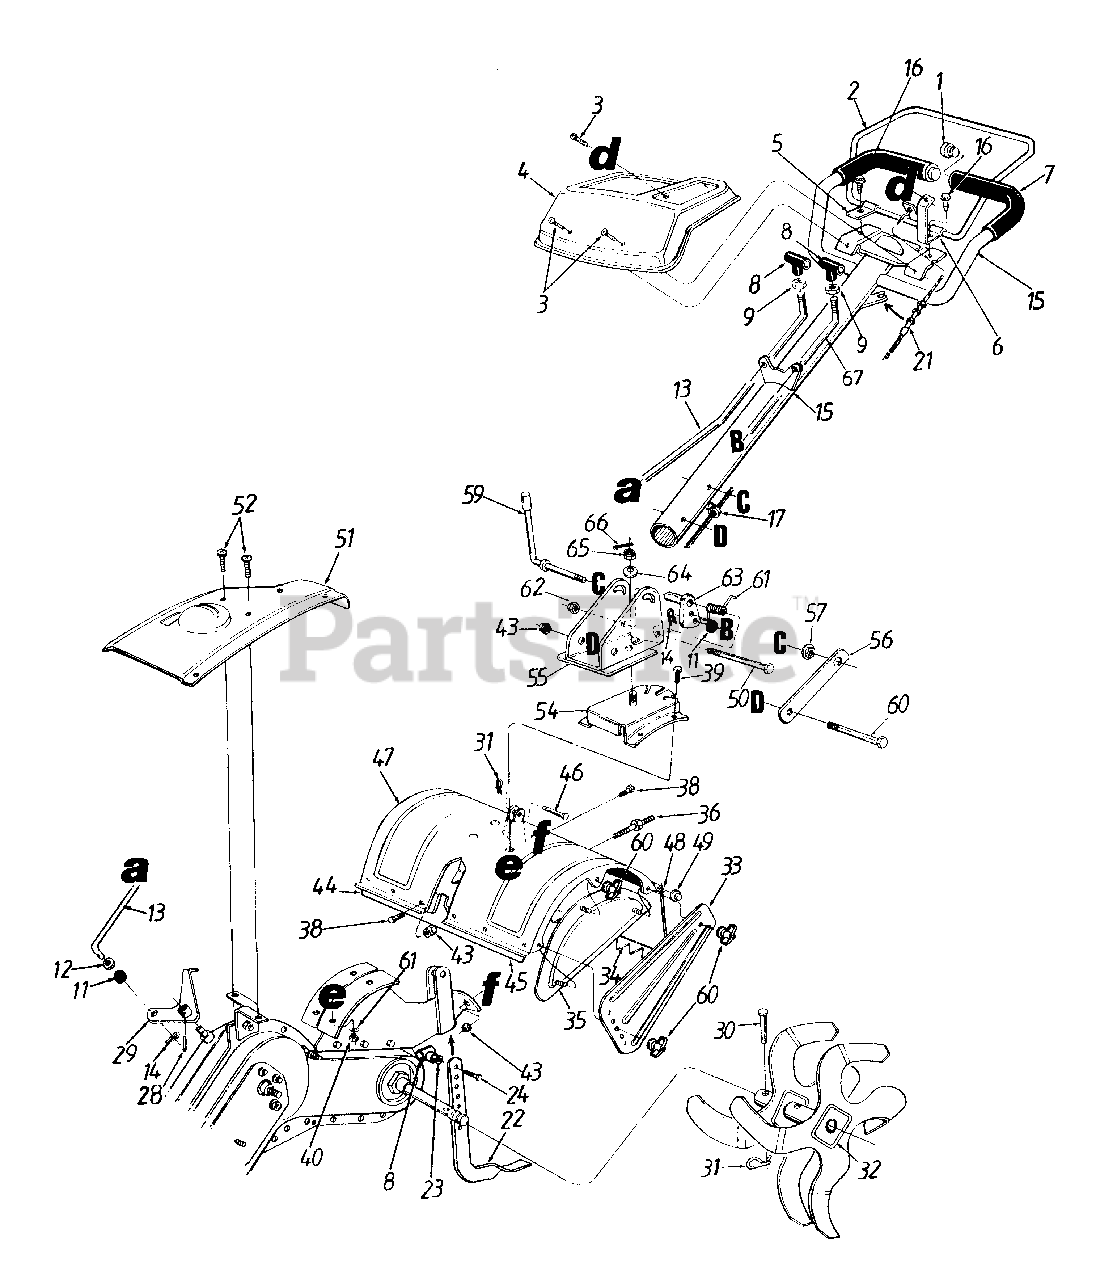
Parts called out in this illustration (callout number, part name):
1	Vinyl End Plug
3	Torx Mach. AB-Tap Scr. 1/4 x .62" Lg.
7	Grip
9	Hex Jam Nut 3/8-16 Thd.
11	Rubber Washer
12	Fl-Wash. .344" I.D. x .6" O.D.
13	Gear Shift Rod
14	Hairpin Clip
17	Cable Clip
21	Clutch Cable
23	Fl-Wash. 3/8" I.D. x 5/8" O.D.
24	Hex Bolt 3/8-16 x 1" Lg.
28	Spiral Pin 3/16" x 1"
31	Hairpin Clip
36	Hex Cap Bolt 5/16-18 x 1.25" Lg.
38	Hex Bolt 5/16-18 x .75" Lg.
39	Carriage Bolt 3/8-16 x 1" Lg.
40	Hex Ins. L-Nut 3/8-16 Thd.
43	Hex Flange Top L-Nut 5/16-18 Thd.
46	Clevis Pin .375" Dia.
49	Cap Speed Nut
50	Hex Bolt 5/16-18 x 3" Lg.
52	Torx Mach. AB-Tap Scr. 1/4 x .6"
57	Hex Flange Nut 3/8-24 Thd.
59	Handle Adjustment Crank
60	Knob 5/16-18 Thd.
61	L-Washer 3/8" I.D.
62	3/8" Nut
63	Handle
64	Bellwasher
65	5/8" Nut
67	Handle, Rod
